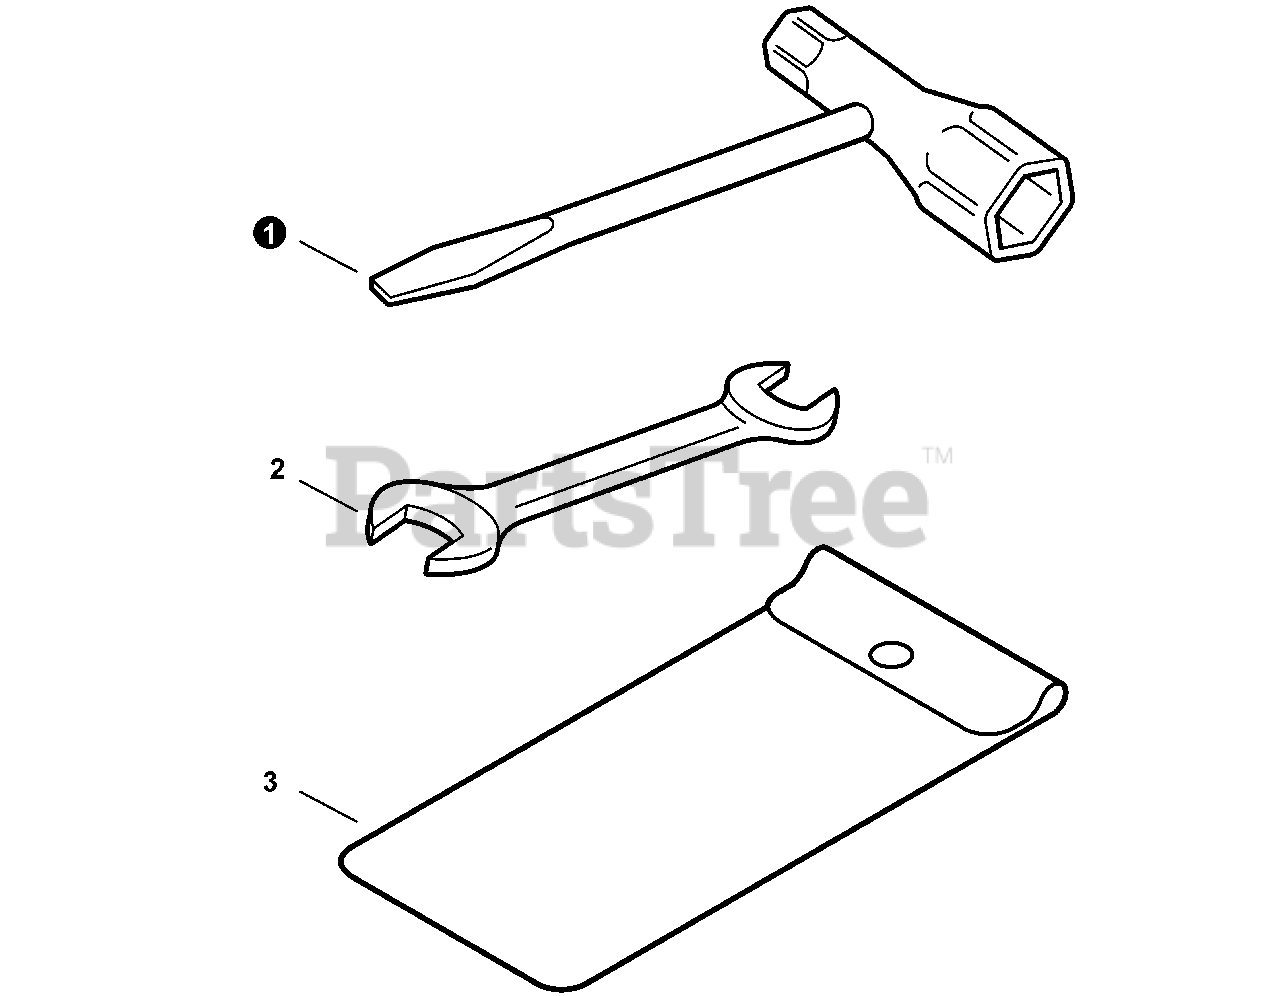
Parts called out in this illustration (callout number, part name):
1	T-WRENCH 17x-19 L200
2	SPANNER 8×10
3	BAG, TOOL
